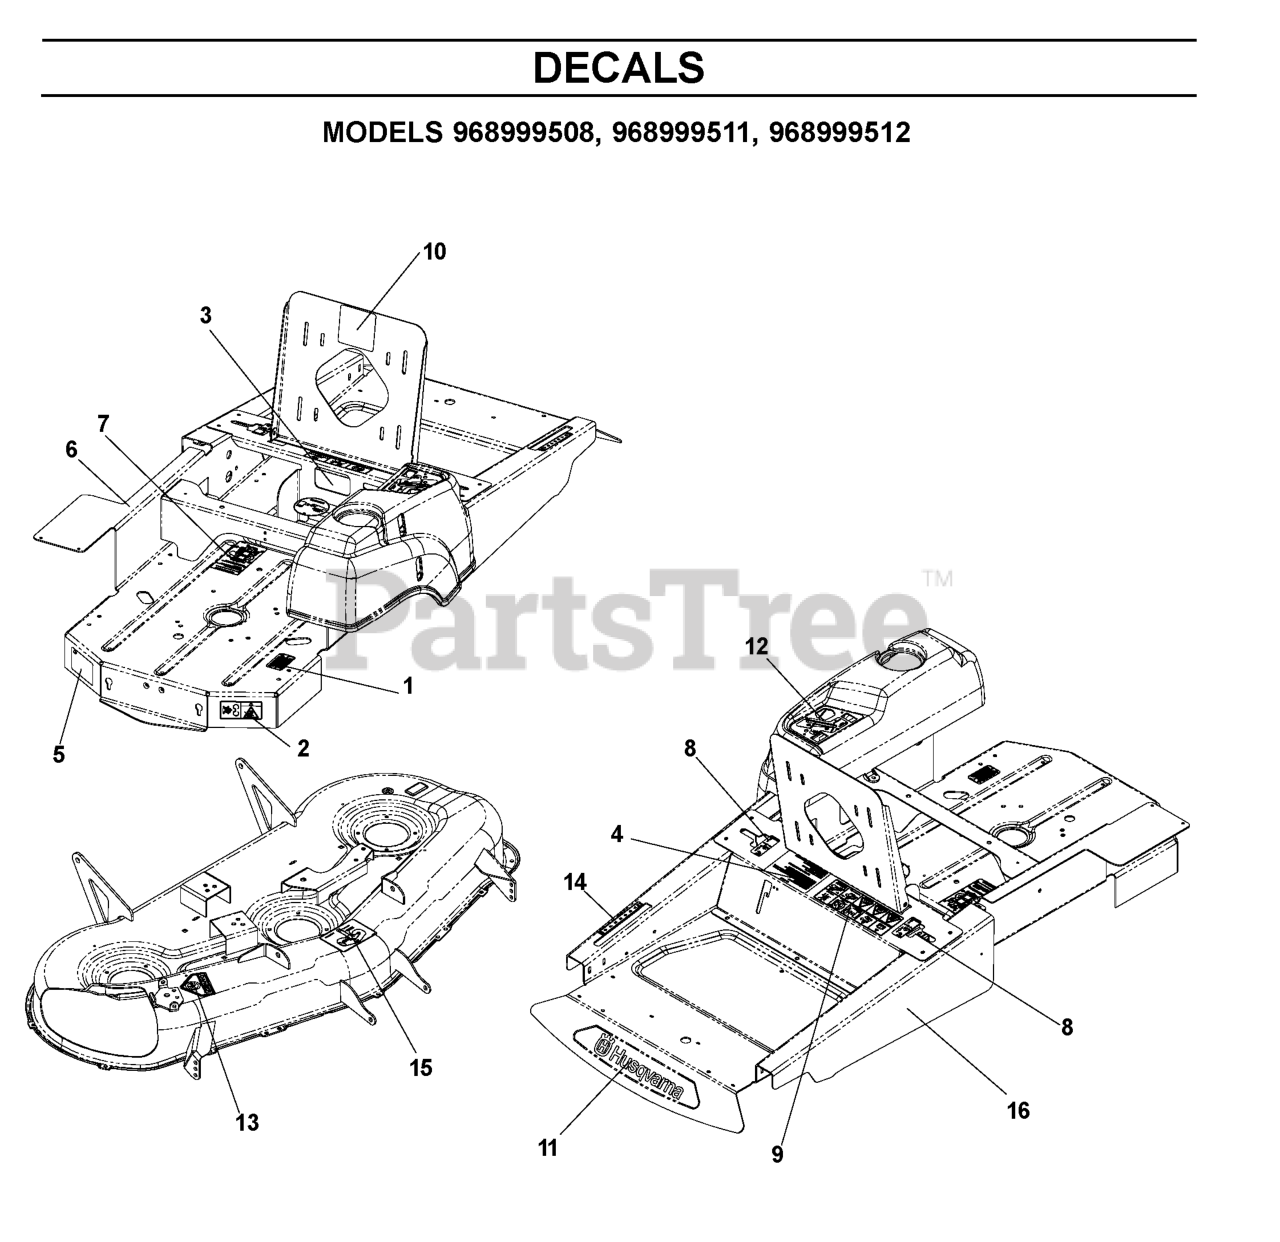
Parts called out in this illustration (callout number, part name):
1	DECAL, PROP. 65
2	DECAL, BELT DRIVE
3	EURO DECAL-BATTERY WARNIN6
4	DECAL, START
5	DECAL, DO NOT TOW
6	DECAL, EXITING MOWER
7	DECAL, SERVICE
8	DECAL, MOTION CONTROL
9	DECAL, SAFETY WARNING
10	DECAL, CUSTOMER RESPNSIBILITY
11	DECAL, HUSQ 12" BLUE
12	DECAL, IGNITION CONSOLE
13	DECAL, CPSC
14	DECAL, HEIGHT
15	DECAL, BELT ROUTING
16	DECAL, Z4219 LH
